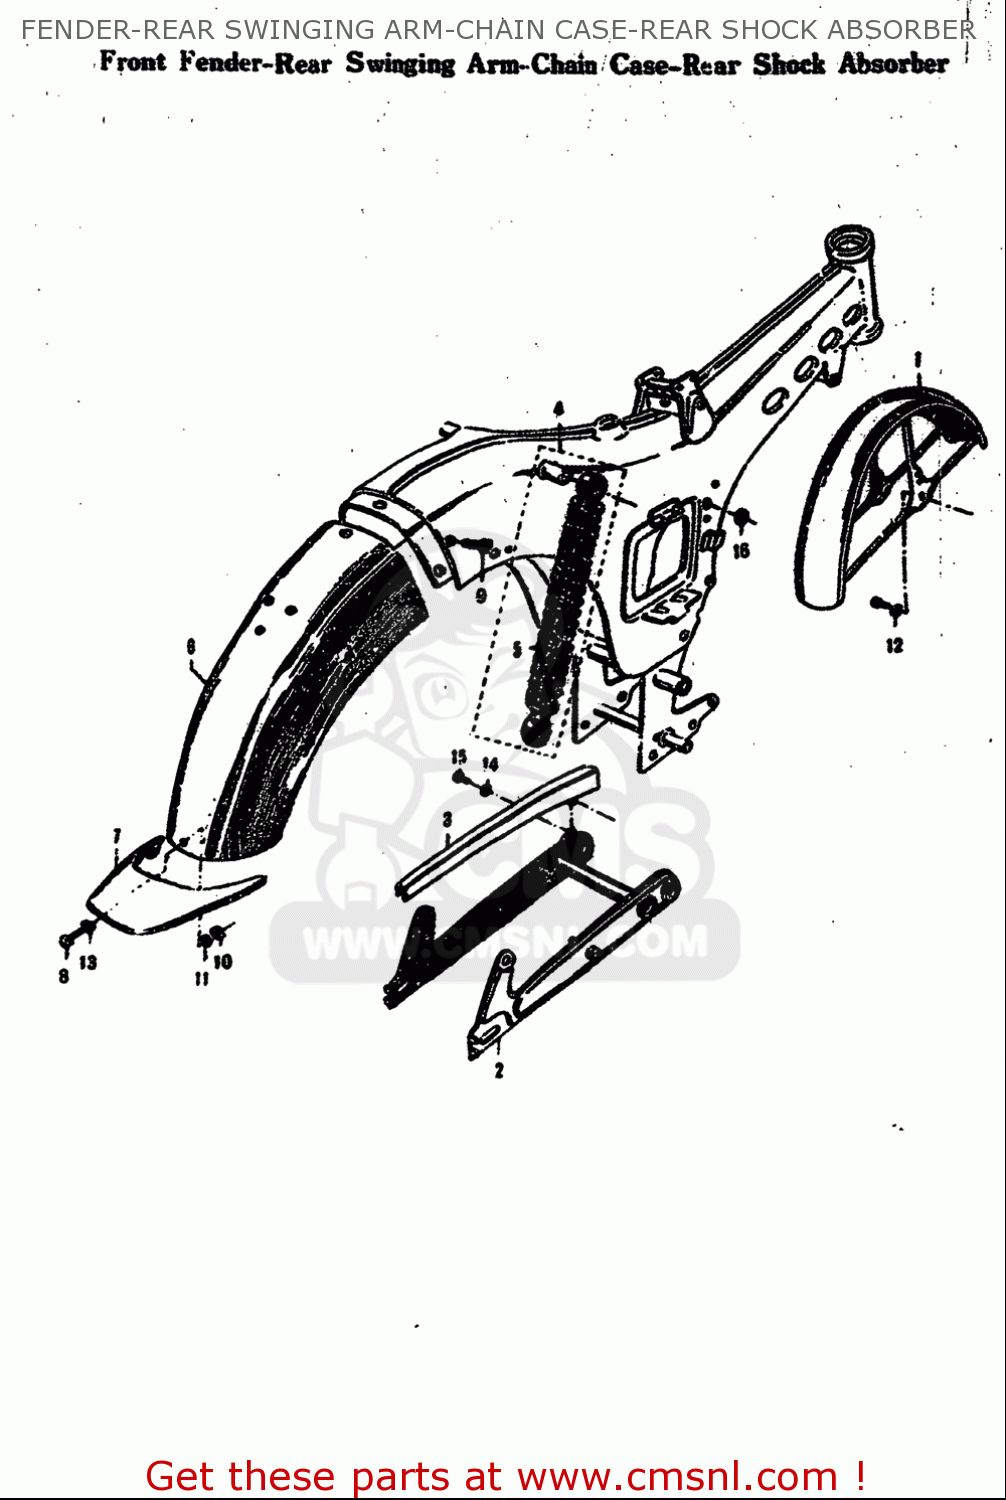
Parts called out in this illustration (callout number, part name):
8	BOLT
9	BOLT
10	NUT
11	WASHER,LOCK
12	WASHER,LOCK
13	WASHER
14	WASHER
